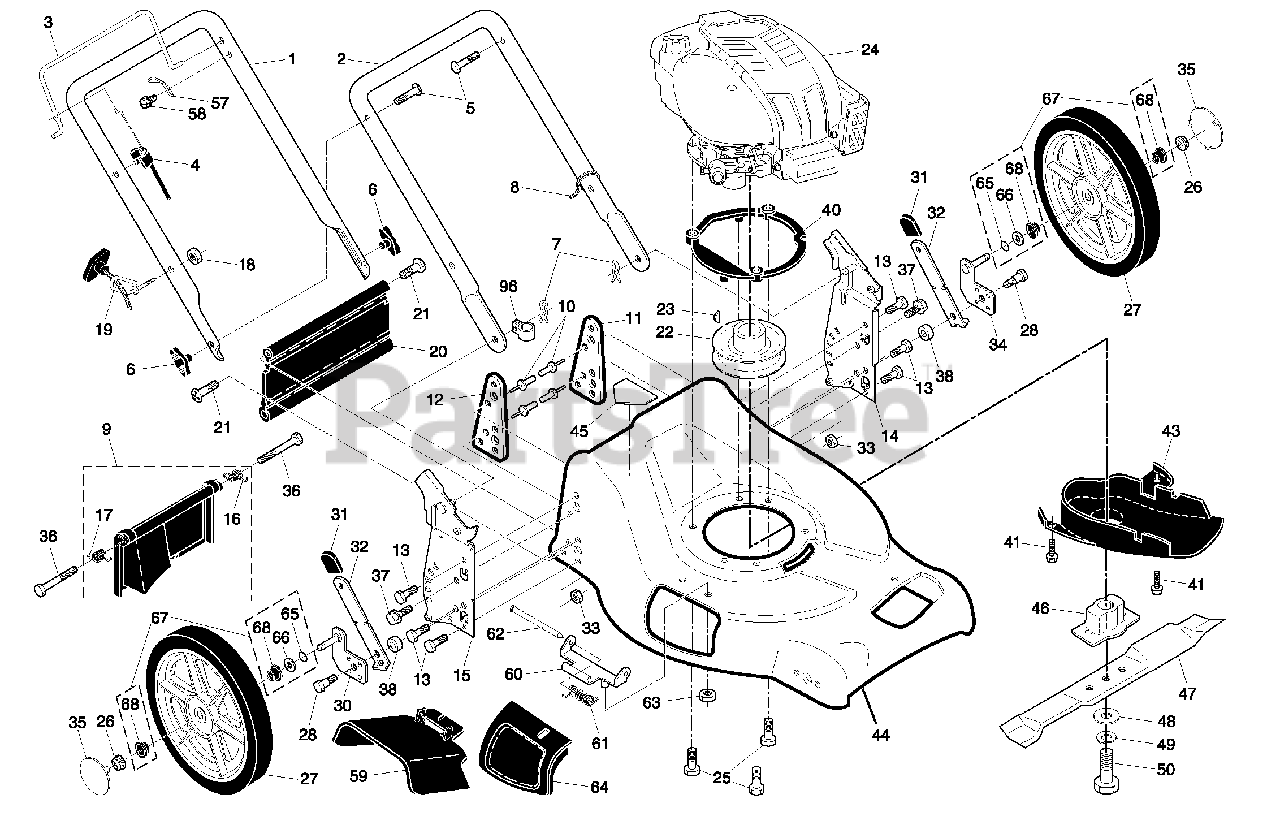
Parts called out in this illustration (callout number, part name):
1	Drive Control Assembly, Complete
3	Pulley
4	Lever
5	Cover, Bottom
6	Screw #8 x .62
7	Mounting Bracket
8	Cap, Bottom
9	Cable, Drive
10	Decal, Drive Control Operation
11	Decal, Drive Control Adjustment (back)
12	E-Ring
13	Pinion Assembly, RH
14	Dust Cover
15	Seal, Friction
16	Washer 1/2 x 1-1/2 x .134
17	Bearing, Wheel Adjuster
18	Selector Knob
19	Disc, Drive
20	Spring, Torsion
21	Pawl
22	Retainer, Drive, LH
23	Pinion, Gear
24	Retainer, Drive, RH
25	Keeper, Belt
26	Screw
27	Pan Head Tapping Screw #10-24 x 2-3/4
28	Drive Cover
29	V-Belt
30	Hubcap
31	Hex Flange Nut
32	Drive Pulley
33	Locknut
34	Wheel & Tire Assembly, Front
35	Kit, Wheel Adjuster, LH
36	Gear Case Assembly, Complete
37	Pinion Assembly, LH
38	Locknut 1/4-20
39	O-Ring
40	Spring
41	Kit, Wheel Adjuster, RH
42	Washer, Flat
54	Grassbag Assembly
55	Driveshaft Cover
57	Frame, Grassbag
60	Decal, Drive Cover
61	Case, Lower
62	Case, Upper
63	Gear, 27 Teeth
66	Shaft, Input
67	Spacer
69	Wire, Formed
70	Bearing, Ball
72	Seal, Output Shaft
73	Washer
75	Bushing
76	Shaft, Output
77	Screw
78	Seal, Input Shaft
